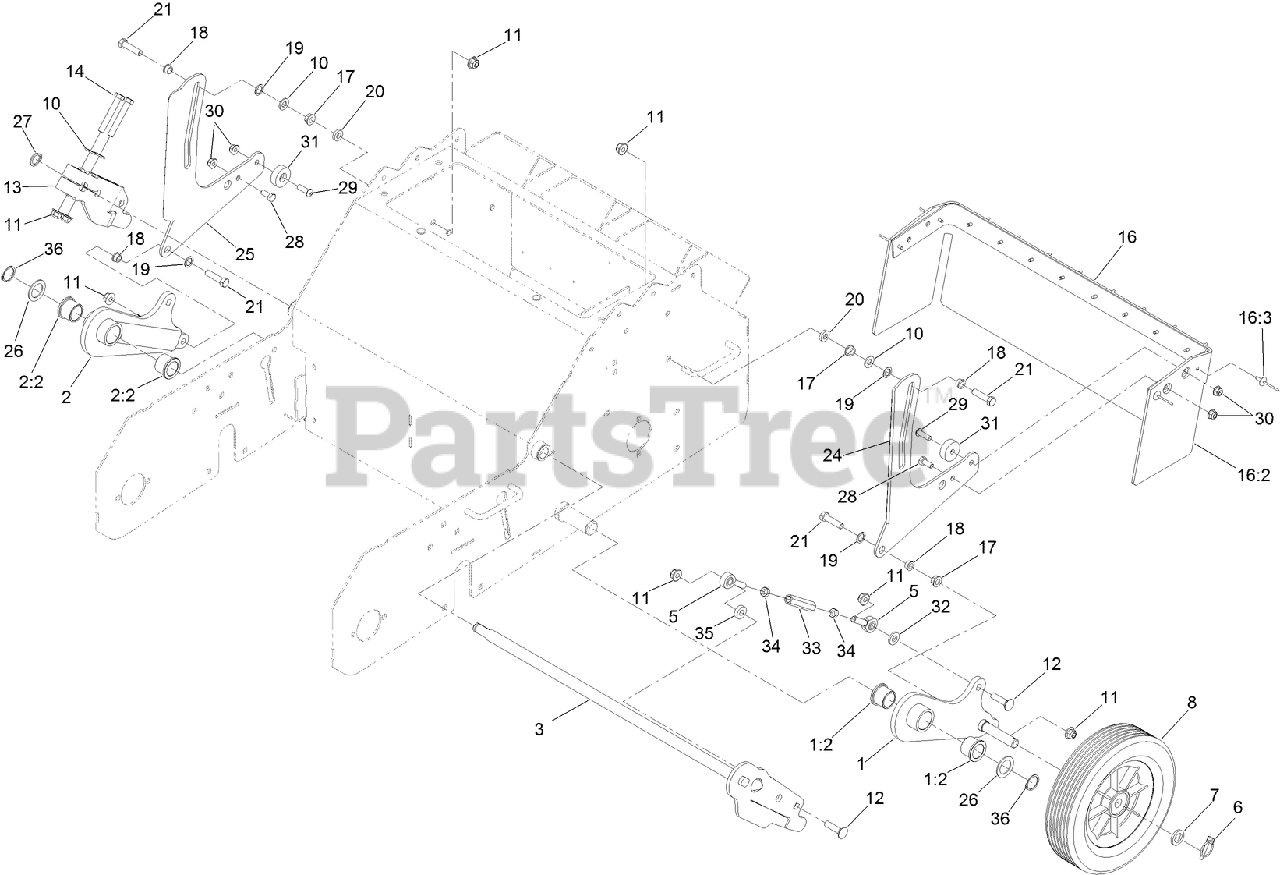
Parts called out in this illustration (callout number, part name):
1	LH WHEEL ARM ASM
1:2	BUSHING-FLANGE
2	RH WHEEL ARM ASM
2:2	BUSHING-FLANGE
5	BALLJOINT
6	PIN-KLIK
7	SPACER-BEARING
8	WHEEL-10 INCH
10	WASHER-FLAT
11	NUT-HF, NI
12	SCREW-CARR
13	ARM-LIFT, RH
14	SCREW-HH
16	GUARD-FOOT
16:2	FOOT-SHIELD
16:3	RIVET-POP
17	NUT-HHF, WHIZ
18	BUSHING-FLANGED
19	WASHER-NYLON
20	SPACER
21	SCREW-HH
24	GUARD-ARM, LH
25	GUARD-ARM, RH
26	WASHER-SPACER
27	RING-RETAINING
28	SCREW-HH
29	SCREW-HSBH
30	NUT-HF, NI
31	GUIDE-ARM, TRAIL
32	WASHER
33	ROD-LIFT LINK
34	NUT-HJ
35	SPACER
36	RING-RETAINING
